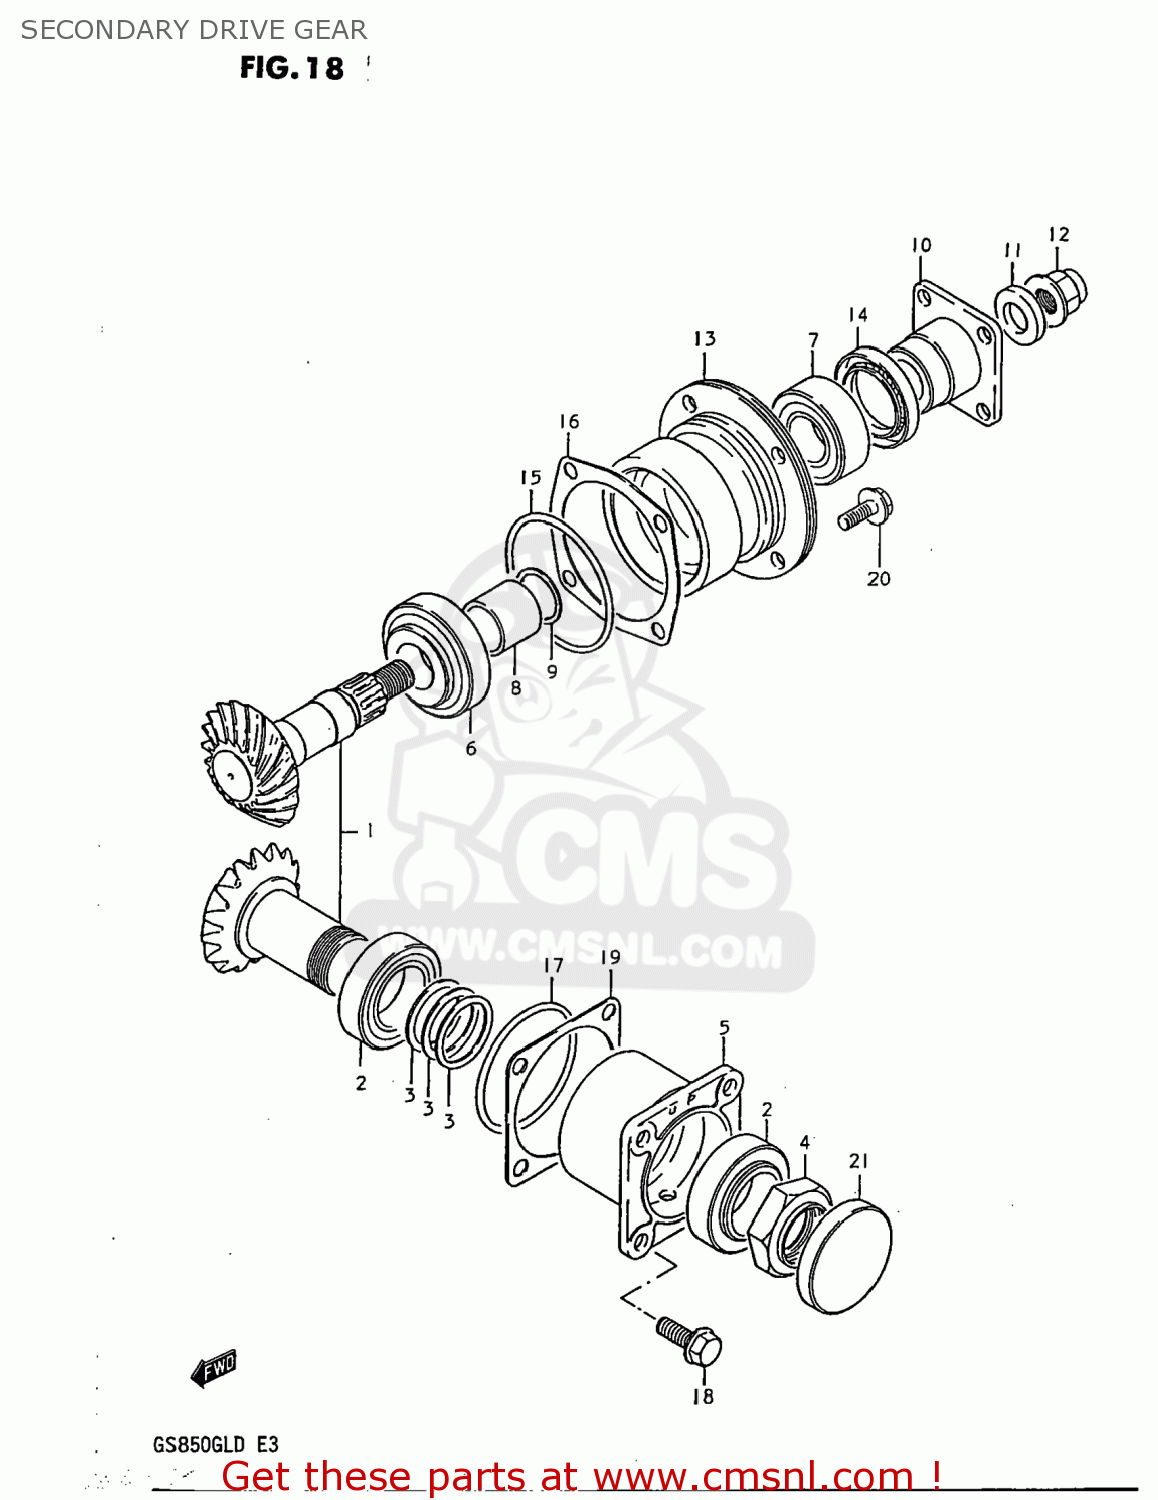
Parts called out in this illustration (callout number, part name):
1	GEAR SET,SECON
2	BEARING(32X58X17)
3	SHIM(32X38X2)
4	NUT
5	HOUSING,SECONDARY DRIVE
6	TAPER,ROLLER BEARING
7	BEARING
8	SPACER (25.2X30X40)
9	SHIM (25X30X2
10	FLANGE,UNIVERSAL JOINT
11	WASHER(14X29X4)
12	NUT
13	HOUSING,SECONDARY DRIVE
14	SEAL,OIL(35X52X9)
15	O RING(D:3.1,ID:69.4)
16	SHIM,DRIVEN GEAR HOUSING
17	O RING(D:2.4,ID:62.6)
18	BOLT
19	SHIM,SECONDARY DRIVE
20	BOLT
21	PLUG
